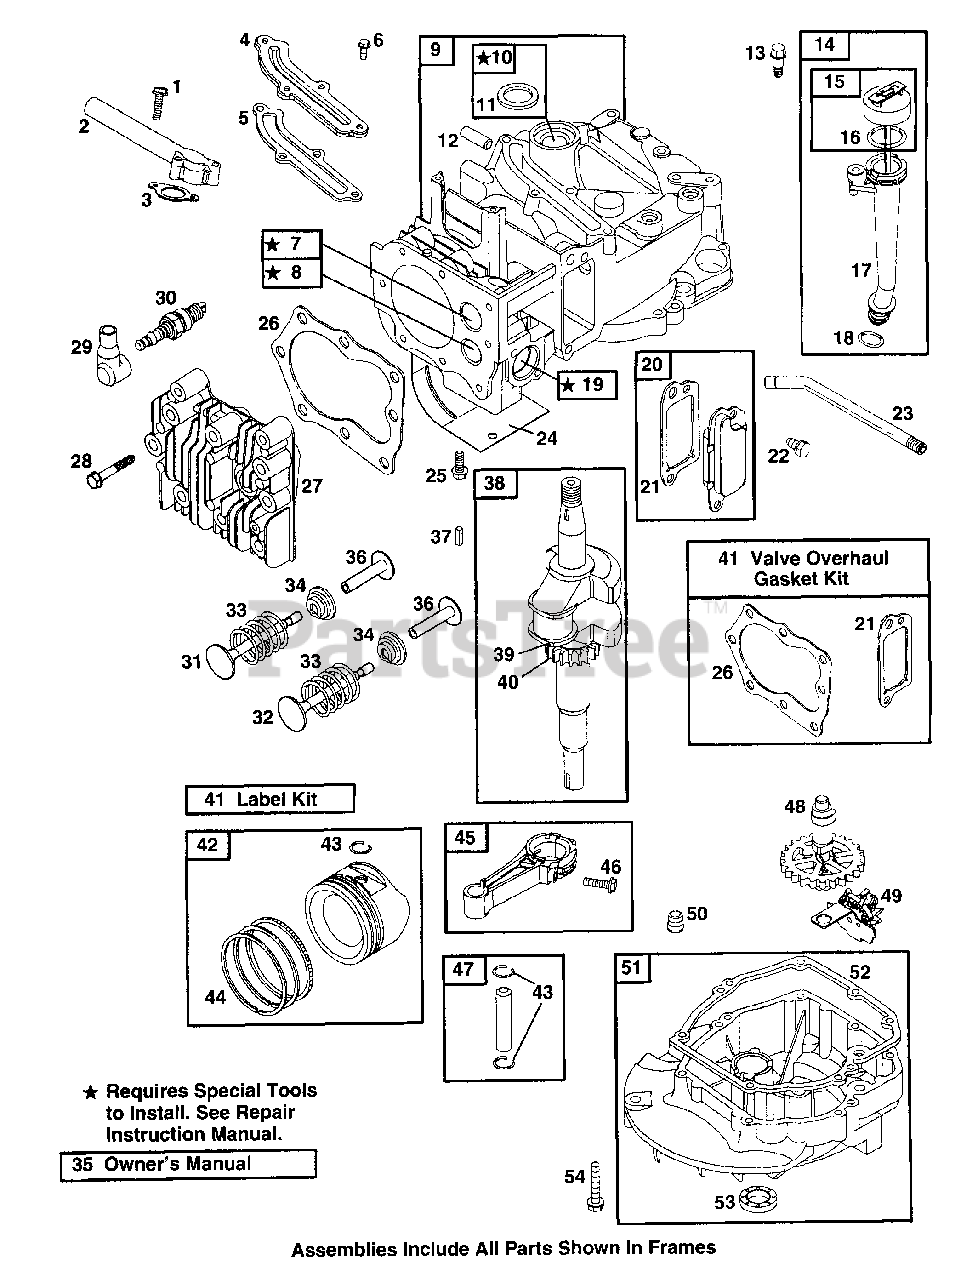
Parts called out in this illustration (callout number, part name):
1	Screw (Intake Manifold)
2	Intake Manifold
3	Intake Gasket
4	Breather Passage Cover
5	Breather Passage Gasket
6	Screw (Breather Passage Cover)
7	Valve Seat (Intake)
8	Valve Seat (Exhaust)
9	Cylinder Assembly
10	Bushing/Seal Kit
11	Oil Seal
12	Locating Pin
13	Screw (Dipstick Tube)
14	Dipstick/Tube Assembly
15	Dipstick
16	Dipstick/Tube Seal
17	Oil Fill Tube
18	Dipstick Tube Seal
19	Guide Bushing (Intake Valve)
20	Breather Assembly
21	Breather Gasket
22	Screw (Breather Assembly)
23	Breather Tube
24	Cylinder Shield
25	Screw (Cylinder Shield)
26	Cylinder Head Gasket
27	Cylinder Head
28	Screw (Cylinder Head)
29	Sparkplug Boot
30	Spark Plug
31	Intake Valve
32	Exhaust Valve
33	Valve Spring
34	Valve Retainer
35	Owner's Manual
36	Valve Tappet
37	Flywheel Key
38	Crankshaft
39	Timing Key
40	Timing Gear
41	Valve Overhaul Gasket Set
42	Piston Assembly (Standard)
43	Piston Pin Lock
44	Ring Set (Standard)
45	Connecting Rod
46	Screw (Connecting Rod)
47	Piston Pin
49	Governor/Oil Slinger
50	Oil Drain Plug
51	Engine Sump
52	Crankcase Gasket
53	Oil Seal
54	Screw (Engine Sump)
